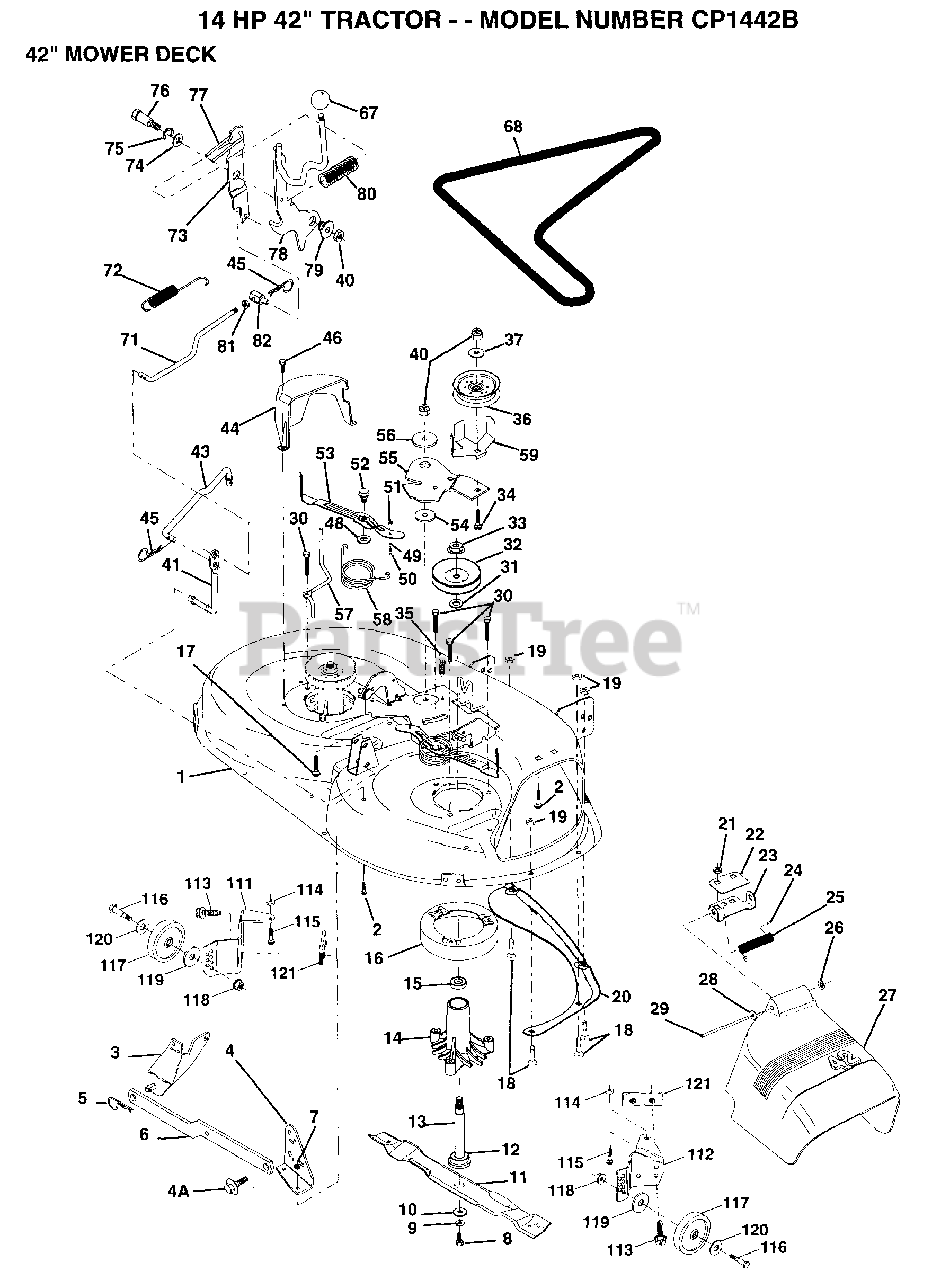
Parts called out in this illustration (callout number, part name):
2	BOLT
3	BRKT ASM SWAY BAR
4	BRKT DECK SW BAR
4A	BOLT SHD 5/16-18
7	NUT
8	BLADE BOLT
10	WASHER.HARD.BLADE
11	"BLADE.42"" MULCHER"
12	BEARING.BALL
14	HSG ASM MANDREL
15	BEARING
16	STRIPPER RND MWR
17	BOLT RDHD 3/8-16
18	BOLT
19	NUT
21	NUT
22	STIFFENER BRKT
23	DEFLECTOR BRKT
24	CAP-SLEEVE LT
25	SPRING TORSION
26	NUT PUSH M
27	DEFLECTOR.SHIELD
28	WASHER
29	HINGE ROD
31	WASHER
34	BOLT
35	XMAS TREE FASTNER
36	FLAT IDLER PULLEY
37	WASHER
40	NUT
41	PIVOT ROD
43	ROD CLUTCH W/NIBS
44	GUARD MAND LH BLK
45	RETAINER M
46	SCREW.1/4-20X5/8
48	HARD SMALL WASHER
50	SHOULDER BOLT
51	LOCKNUT
52	BOLT.SHLD.5/16-18
53	BRAKE PAD ARM ASM
54	HARDENED WASHER
56	SPACER RETAINER
57	KEEPER BELT LH 42
58	SPRING TORSN BRAK
59	GUARD IDLER TUV
68	BELT-V MWR 82.625
71	ROD CLUTCH 38/42
72	RETURN SPRING
73	CLUTCH ARM SECOND
74	WASHER
75	RING
76	SHOULDER BOLT
77	SPRING KEEPER
78	LEVER ASM CLT PRM
79	BUSHING
81	NUT
82	TRUNION ADJ
83	KNOB T (1/2-HOLE)
113	SCREW
116	BOLT M
117	WHEEL.GAGE.BLK.PL
118	LOCKNUT
119	WASHER
120	WASHER
121	BRACKET.EXTRD.GWL
